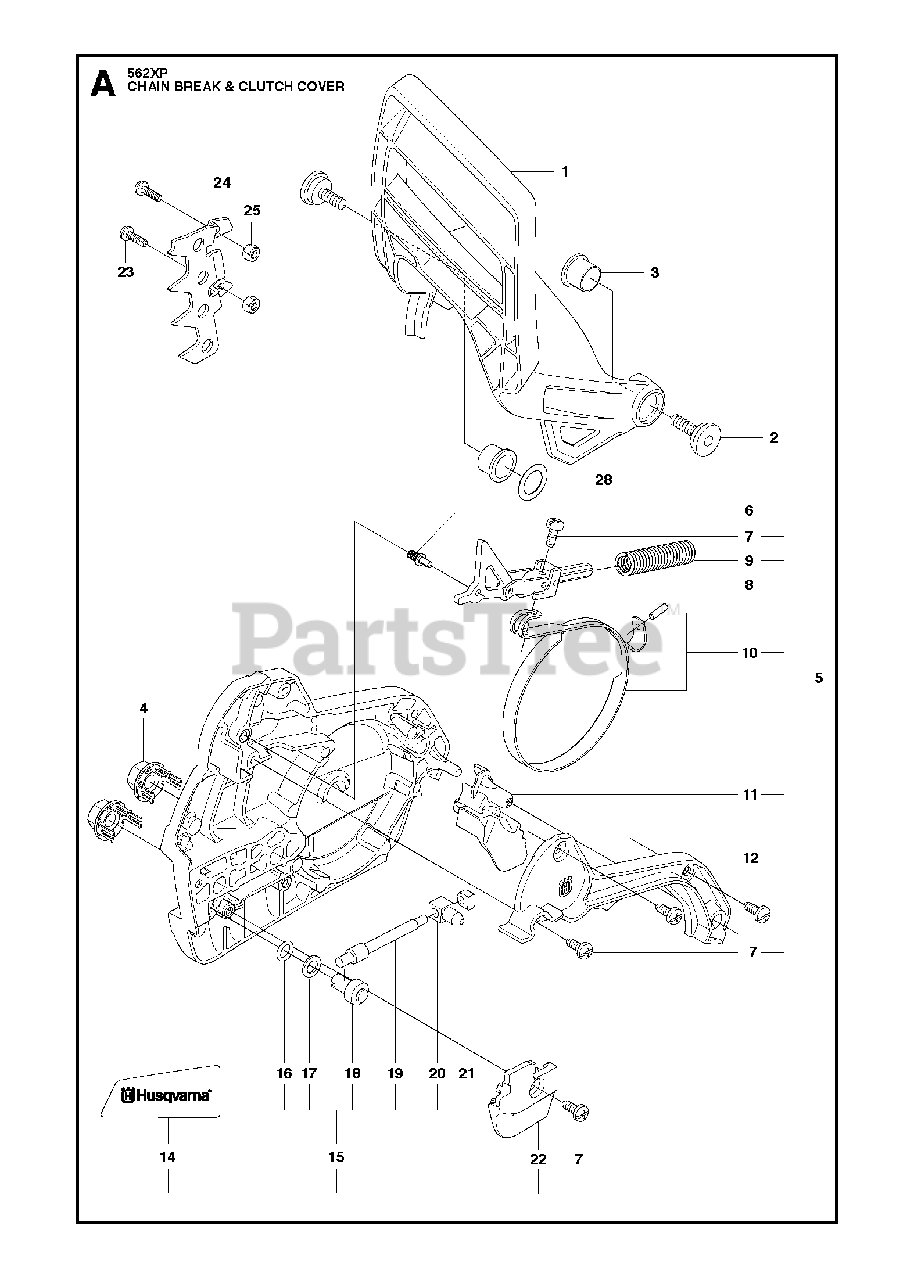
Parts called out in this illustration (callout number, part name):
1	HAND GUARD
4	NUT RETAINER ASSY
5	CLUTCH COVER ASSY
6	PIN
7	SCREW
8	KNEE JOINT ASSY
9	SPRING
10	BRAKE BAND ASSY
11	GUARD
12	COVER
14	LABEL
15	CHAIN TENSIONER KIT
16	O-RING
17	WASHER
18	WORM WHEEL
19	WORM SCREW
20	PAWL
21	WORM WHEEL
22	CHAIN GUIDE
24	SPIKE OUTER
25	SPIKE OUTER
